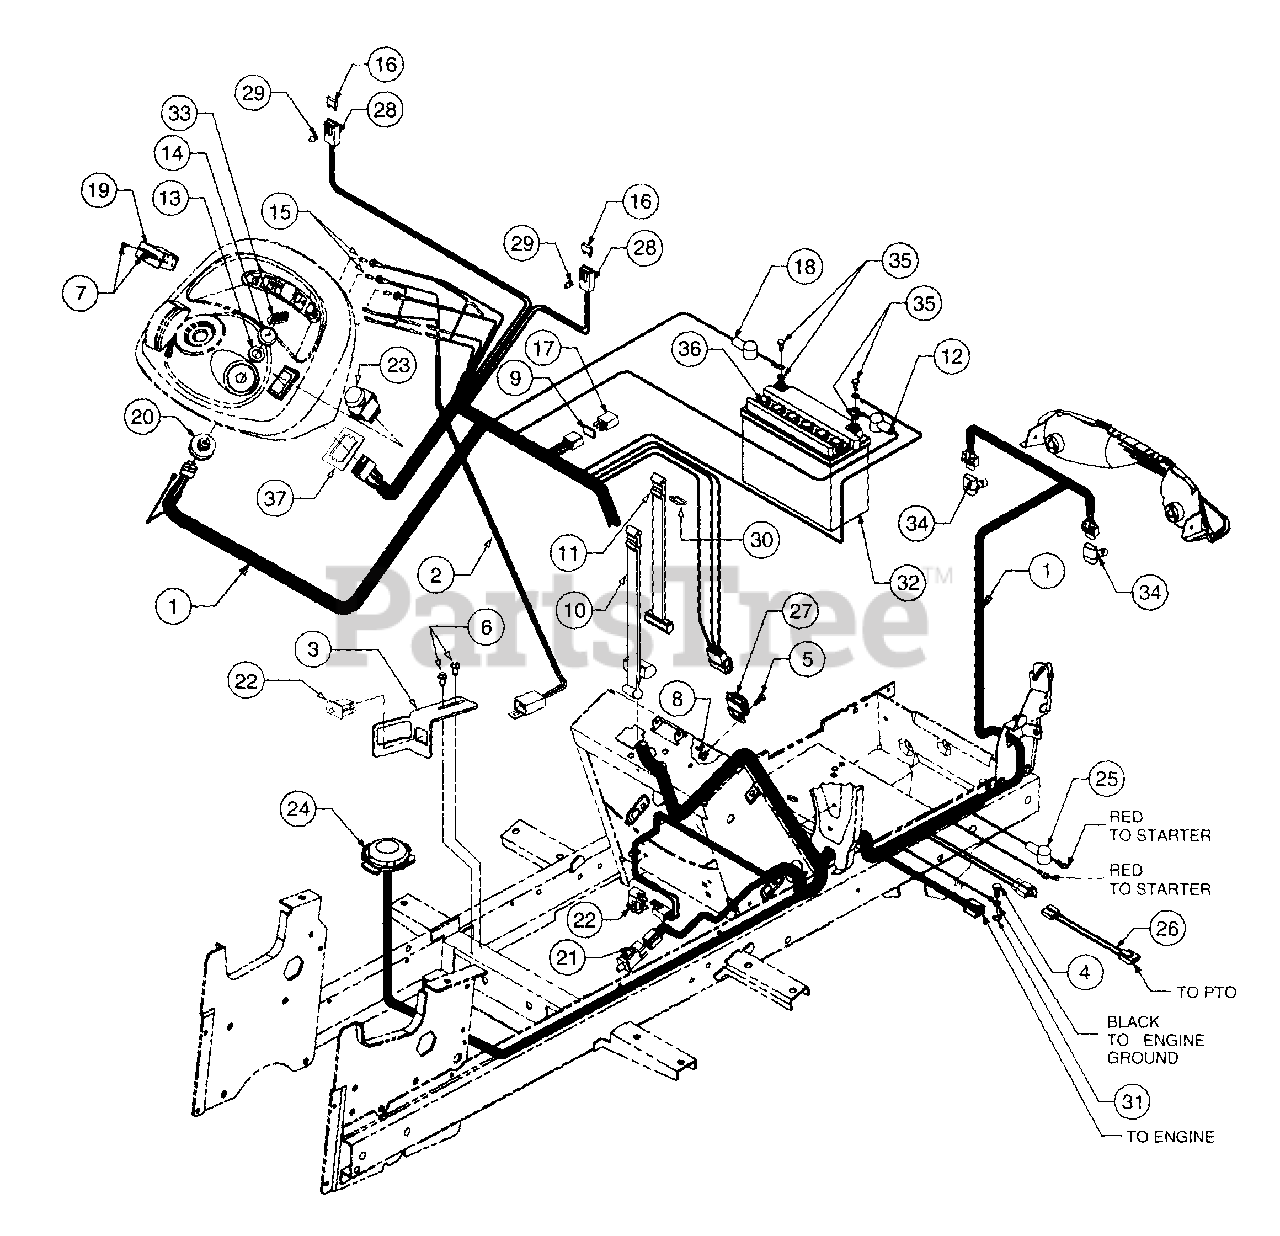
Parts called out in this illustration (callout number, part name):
1	Wire Harness, Main
2	Wire Harness, Indicator Light
3	Bracket, Clutch Switch
4	Screw, Hex Cap, 5/16-24 x .62
5	Screw, Hex Cap, 1/4-20 x .625 GR5
6	Screw, Hex Wash Hd Tapp, 1/4-20 x .5
7	Screw, Truss Hd Tapp, #6 x .62
8	Nut, Hex Sems, 1/4-20
9	Gasket, Silicone
10	Strap, Battery Retainer
11	Strap, Battery Retainer
12	Cover, Terminal Black
13	Nut, Ignition Switch
14	Cap, Ignition Switch
15	Bulb, Indicator
16	Fuse, 20 Amp
17	Relay
18	Cover, Terminal Red
19	Hour Meter
20	Switch, Ignition
21	Switch, Interlock (Brake)
22	Switch, Snap Mount
23	Switch, PTO
24	Switch, Seat
25	Cover, Terminal Red
26	Adapter, PTO Harness
27	Module, Voltage Sensor
28	Holder, Fuse
29	Clip, Fuse Holder Mounting
30	Hook, Wire Rectangular
31	Washer, External Lock, 5/16
32	Battery
33	Key, Ignition (Set of 2)
34	Bulb, Head Lamp
35	Battery Cable Hardware (Set of 2)
36	Cap, Battery
37	Bracket, PTO Switch Retainer
